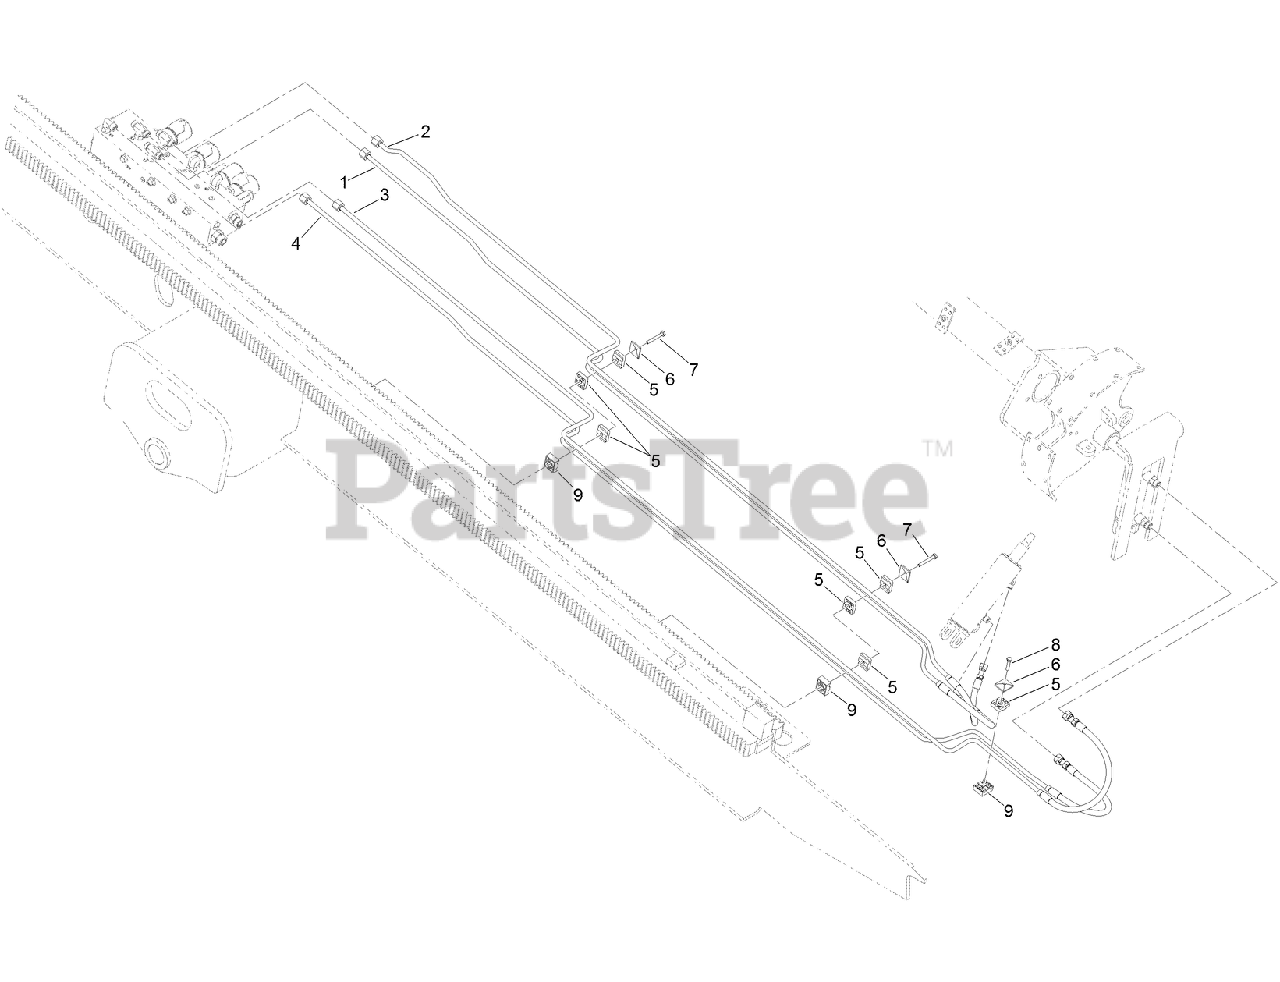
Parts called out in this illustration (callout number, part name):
1	HYD TUBE-HOSE ASM
2	HYD TUBE-HOSE ASM
3	HYD TUBE-HOSE ASM
4	HYD TUBE-HOSE ASM
5	CLAMP-TUBE
6	PLATE-CLAMP, RETAINER
7	SCREW-HH
8	SCREW-HH
9	CLAMP-HOSE
